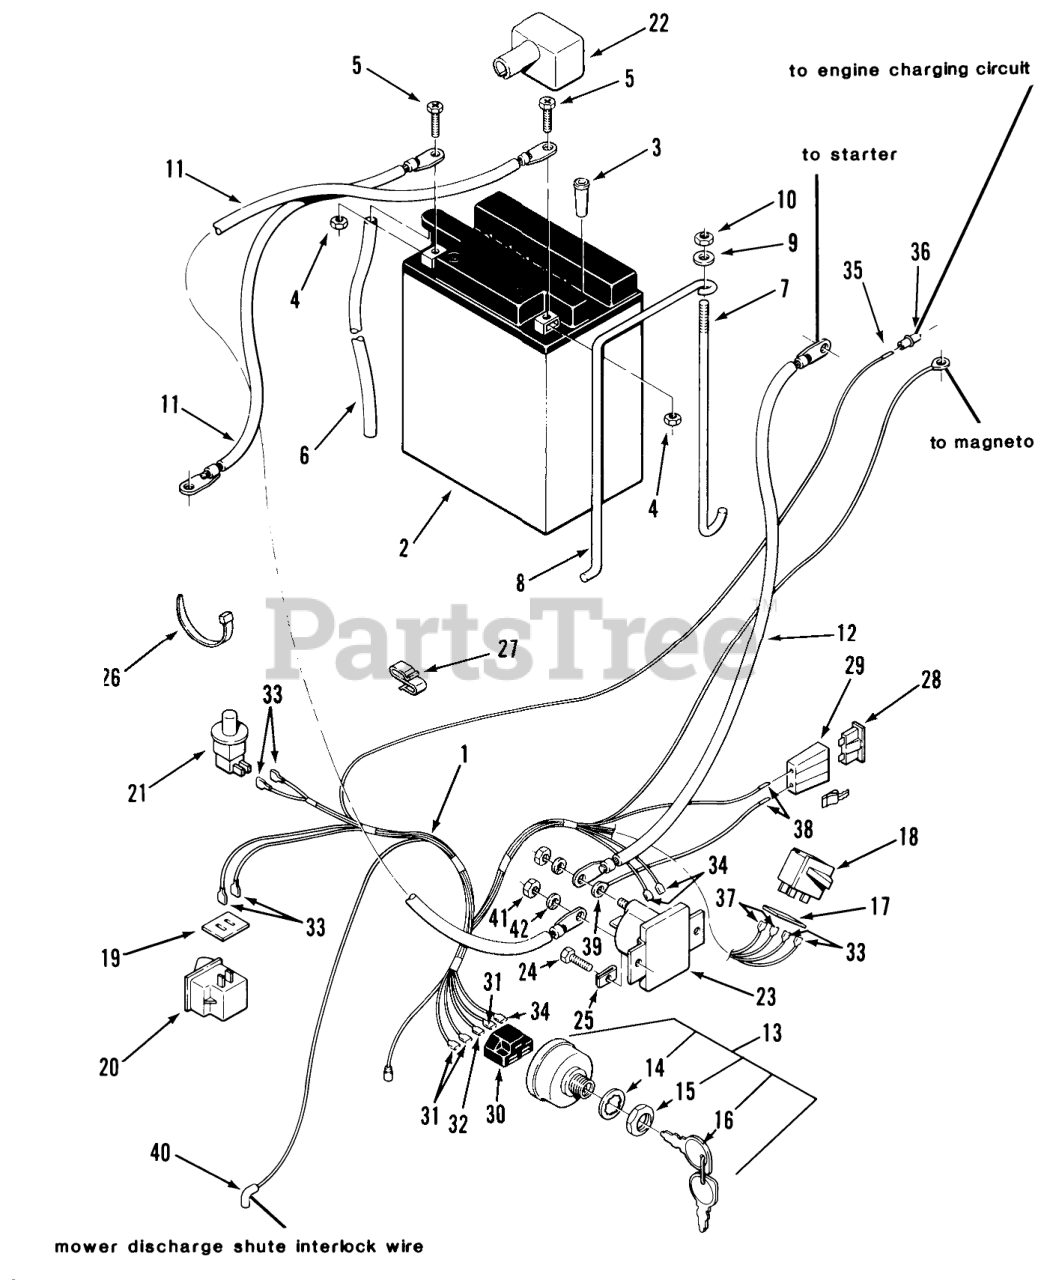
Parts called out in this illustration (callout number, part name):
1	Wiring Harness
2	BATTERY 120CCA
3	ADAPTER
4	Metric Nut 6mm x 1.Omm
5	Metric Bolt 6mm x 1.Omm x 12mm
6	HOSE BATTERY DRAIN
7	HOOK-BATTERY RETAINR
8	Front Battery Hold Down Rod
10	Nut
11	Wire
12	Solenoid To Engine Starter Cable
13	ASSY-SWITCH IGNITION
14	LOCKWASHER
16	Key-EL
17	SHIELD-DIRT (DPDT)
18	PTO Interlock Switch
19	SHIELD-DIRT SPST
20	SWITCH INTERLOCK
21	SWITCH (N.C.)
22	Boot
23	Solenoid
24	Screw
25	Speed Nut
26	PLASTIC TIE
27	CLIP-CABLE
28	FUSE-BLADE, 15 AMP
29	AUTO-FUSEBLOCK TERM
30	CONNECTOR-5 WAY-SERV
31	Terminal
32	TERMINAL-TAB RCPT
33	Terminal
34	Connector
35	Terminal
36	SOCKET HOUSING
37	Wire Terminal (Part of 1)
38	TERMINAL-FUSE
39	Wire Terminal (Part of 1)
40	Terminal Part of 5
41	Nut
42	Washer
